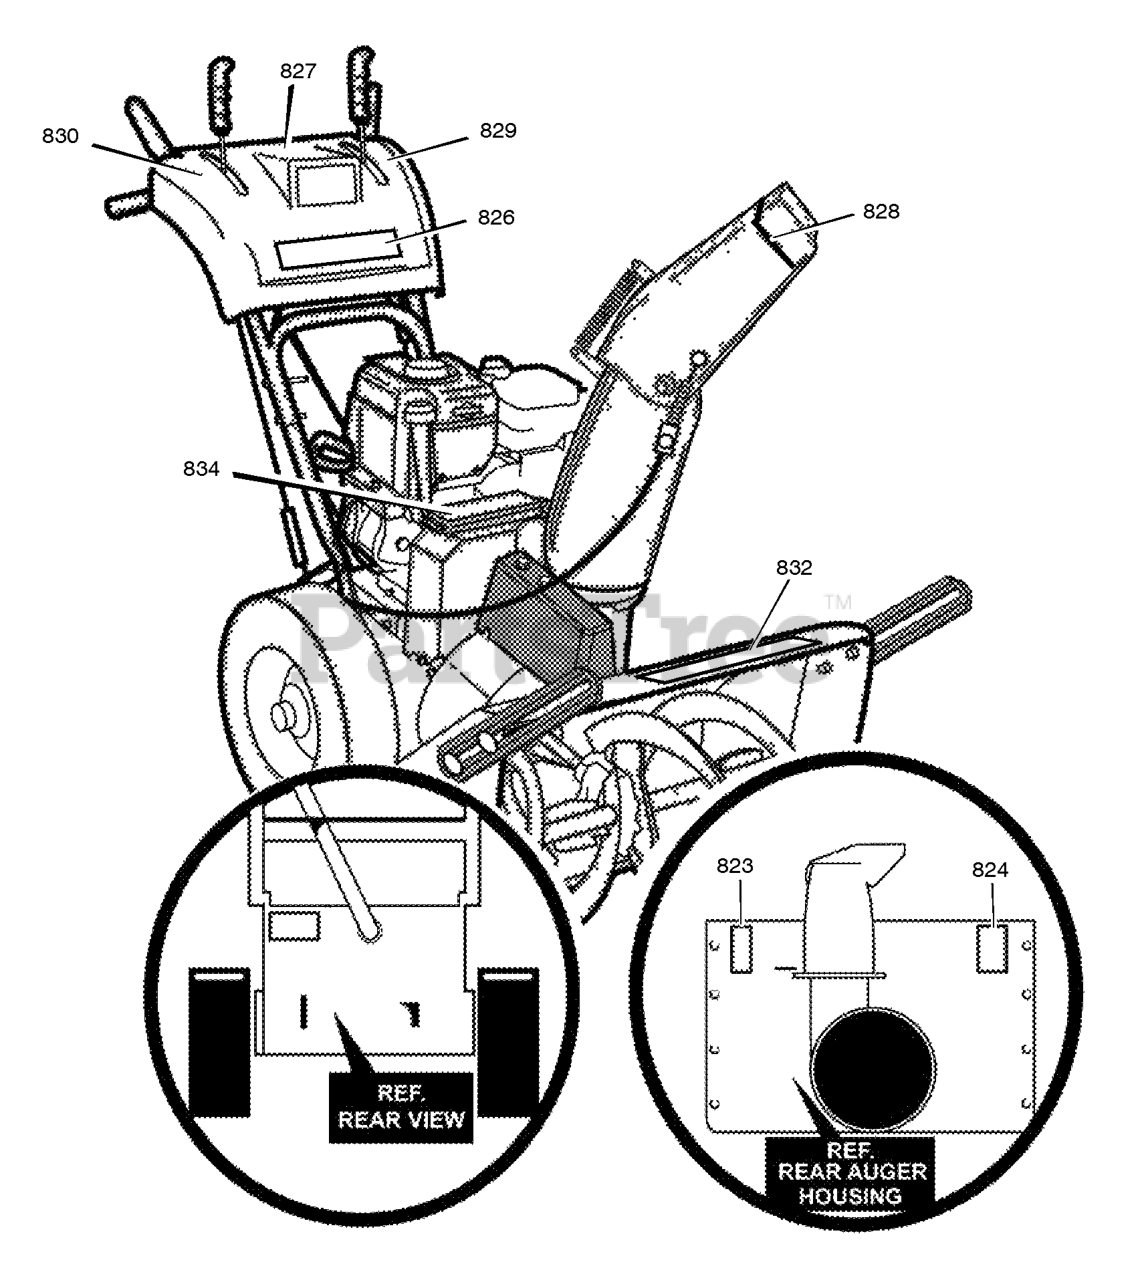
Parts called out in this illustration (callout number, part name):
823	DECAL, DANGER CHUTE HAND
824	DECAL, DANGER FOOT
826	NAMEPLATE, CRAFTSMAN
827	DECAL, SINGLE HAND CONTROL
828	DECAL, DANGER
829	DECAL, DRIVE CLUTCH
830	DECAL, TRANS
832	DECAL, CRAFTSMAN 11.5/30
834	DECAL, TOOLBOX INFORMATION
